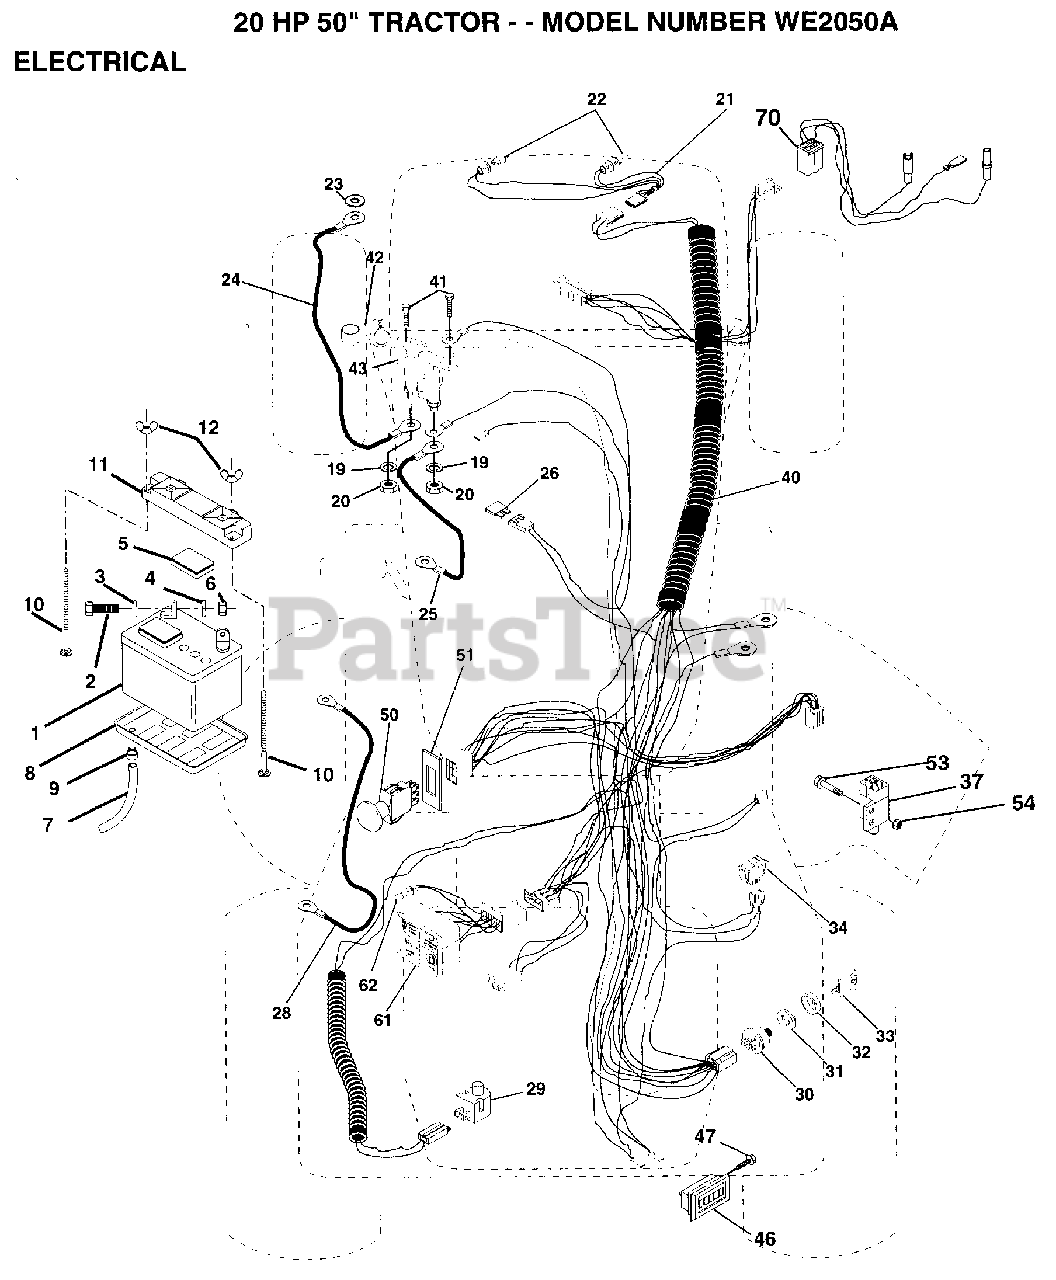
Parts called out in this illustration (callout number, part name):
2	BOLT LT
3	WASHER
4	LOCKWASHER
5	"CAP,BATTERY "
7	"DRAIN TU T, BATT"
8	"TRAY T, BATTERY"
9	HOSE CLAMP T
10	BOLT
20	NUT
22	HEADLAMP BULB
23	LOCKWASHER
24	"CABLE T, BATTERY"
25	CABLE-BATTERY T
26	FUSE HYT
29	SWITCH SEAT
32	COVER KEY SWITCH
33	KEY MLD GEN DELTA
34	SWITCH LT
37	SWITCH INTERLOCKT
40	HARNESS IGNITION
41	SCREW
46	HOUR METER T
47	SCREW
51	RING RETAIN PTO
53	SCREW
54	"NUT,KEPS"
61	LIGHT.PKG.ASM.
62	BULB LIGHT T
70	HARNESS.ENG.VANII
